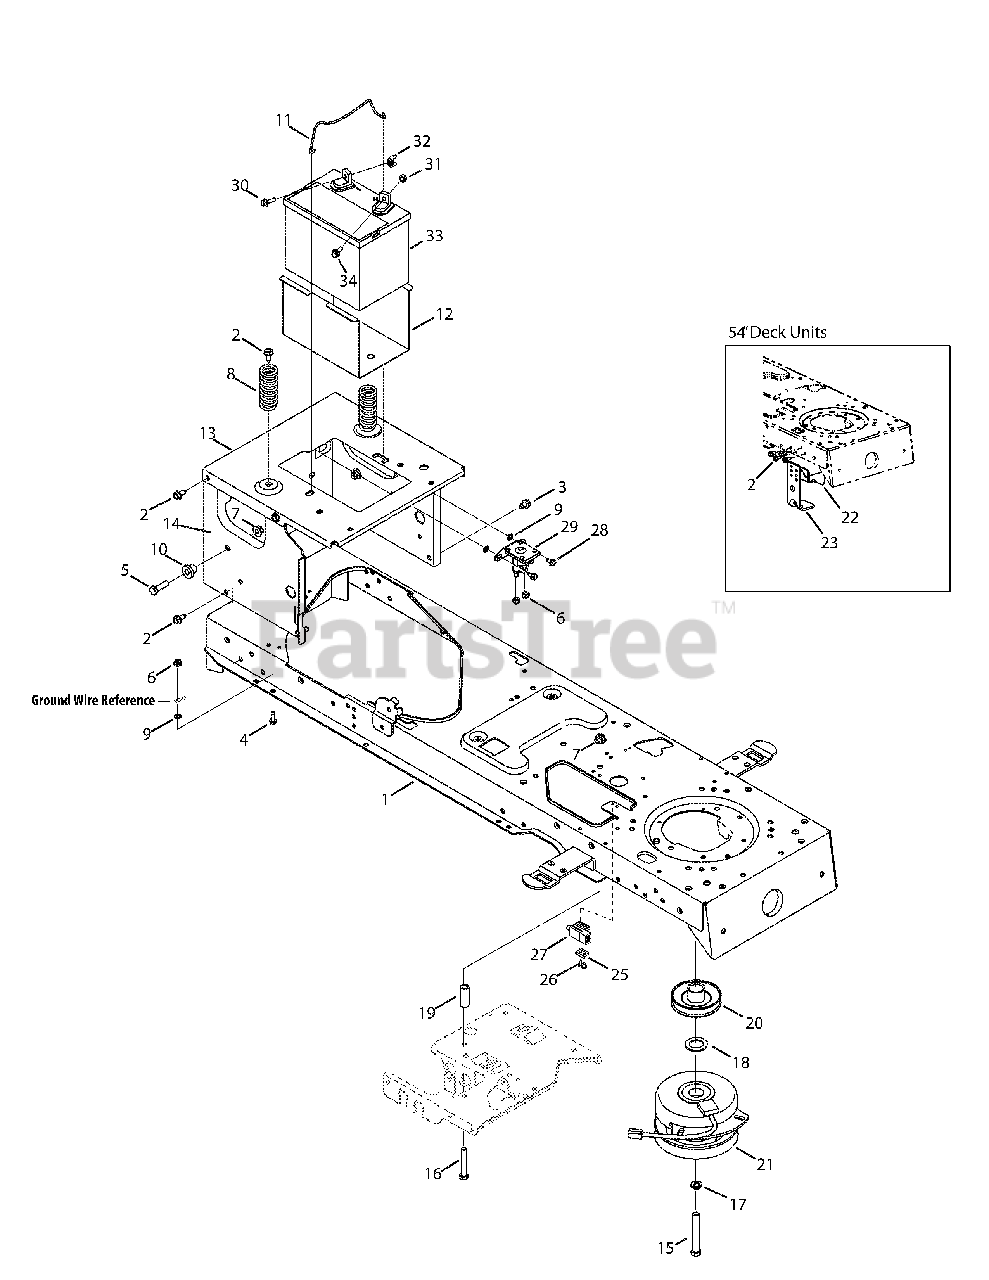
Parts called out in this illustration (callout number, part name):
3	Screw, 5/16-18, 0.500
4	Screw, 1/4-20, 0.750
5	Screw, 3/8-16, 1.25, Gr5
6	Nut, Flange Lock, 1/4-20
7	Nut, Flange Lock, 3/8-16
8	Spring, Compress., 1.28 x 3.125
9	Washer, Lock, 1/4, External
10	Spacer, Shoulder,.38 x 1.0 x.70
11	Hold Rod, Battery
15	Screw, 7/16-20, 3.50, Gr5, Lock
16	Screw, 3/8-16, 2.25, Gr5
17	Lock Washer, 7/16
18	Washer, Flat, 1.031 x 1.620 x.095
19	Spacer,.385 ID x.635 OD x 1.54
20	Pulley, Engine, 3.56 Diameter
21	PTO Clutch, Electric
25	Switch Plate
26	AB Screw, #10-16 x.500
27	Switch
28	Screw, 1/4-20, 0.50
29	Solenoid, 12V, 100 Amp
30	Hex Flange Bolt, 1/4-20,.75
31	Nut, Sems, 1/4-20
32	Nut, Wing, 1/4-20
33	Battery, 235 CCA
34	Screw, Shoulder,.250 x.15, 1/4-20
